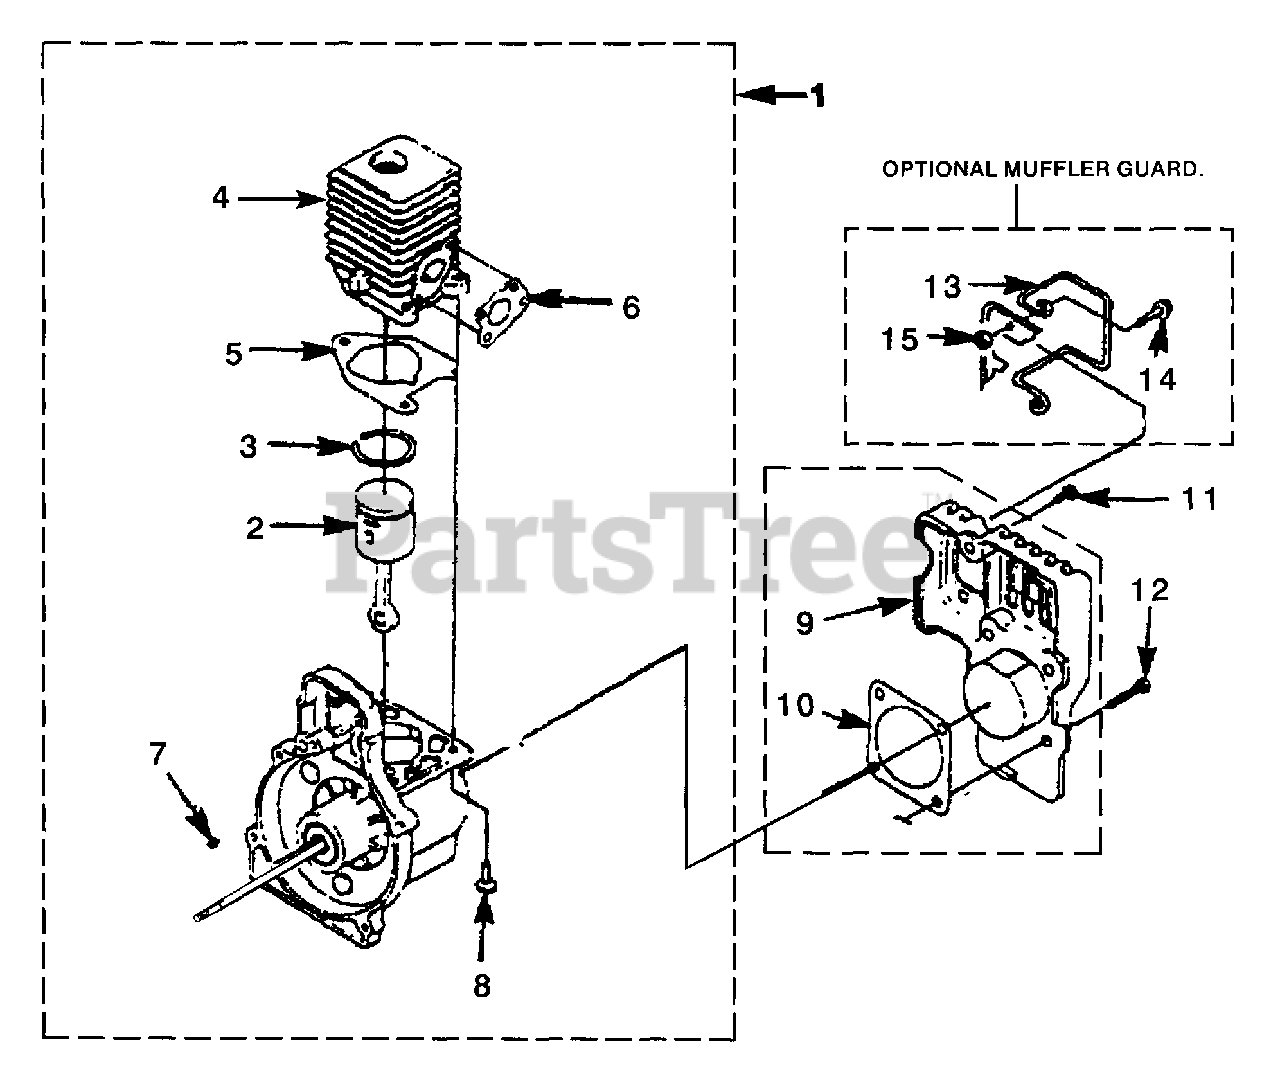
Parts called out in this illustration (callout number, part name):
1	SHORT BLOCK
2	25CC PISTON & ROD
3	RING - Piston
4	25CC CYLINDER KIT
5	GASKET - Cylinder
6	GASKET - Heat Dam
7	KEY - Woodruff
8	SCREW - Thread Forming (10-24 X 3/4")
9	CRANKCASE COVER
10	GASKET - Crankcase Cover
11	SCREW - Plastite (#10 X 1/2")
12	SCREW - Taptite (10-24 X 1/2")
13	WIRE GUARD KIT
14	SCREW - Hex Sems (10-24 X 1/2")
15	NUT (10-24)
